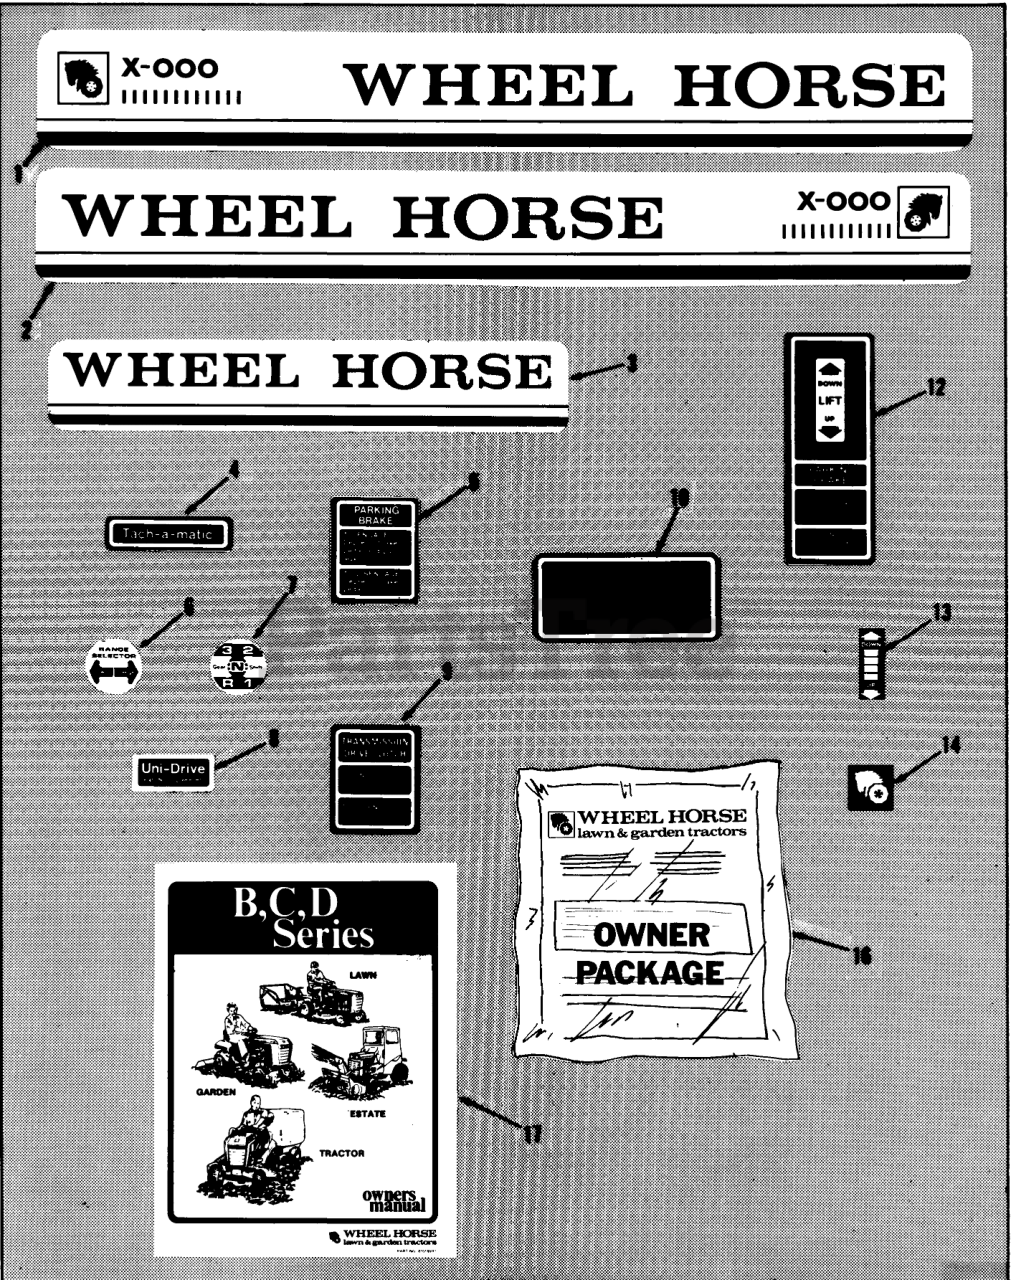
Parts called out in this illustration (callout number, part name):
1	Decal LH C-125 Automatic
1	Decal LH C-145 Automatic
1	Decal LH C-165 Automatic
1	DECAL-HOOD C-175 LH
1	Decal LH C-85 8-Speed
1	Decal LH C-105 8-Speed
1	Decal LH C-125 8-Speed
1	Decal LH C-145 8-Speed
1	Decal LH C-165 8-Speed
1	Decal LH C-175 Twin 8-Speed
2	Decal RH C-125 Automatic
2	Decal RH C-145 Automatic
2	Decal RH C-165 Automatic
2	Decal RH C-175 Twin Automatic
2	Decal RH C-85 8-Speed
2	DECAL-HOOD C-105 RH
2	DECAL-HOOD C-125 RH
2	Decal RH C-145 8-Speed
2	Decal RH C-165 8-Speed
2	Decal RH C-175 Twin 8-Speed
3	DECAL-REAR
4	DECAL-TACHAMATIC
5	DECAL-PARKING BRAKE
6	DECAL HI-LO
7	DECAL-SHIFT
8	Decal-Unidrive
9	Decal-Transmission Clutch
10	Decal-Maintenance
12	Decal-Parking Brake & Lift
13	Decal-Height Control
14	DECAL-LOGO
15	Decal-Taillight C-165, C-175 Twin Only
16	Loose Parts Package C-105, C-125, C-145 Only
16	Loose Parts Package C-165 Only
16	Loose Parts Package C-175 Twin Only
16	Loose Parts Package C-85 Only
17	Owner-s Manual
